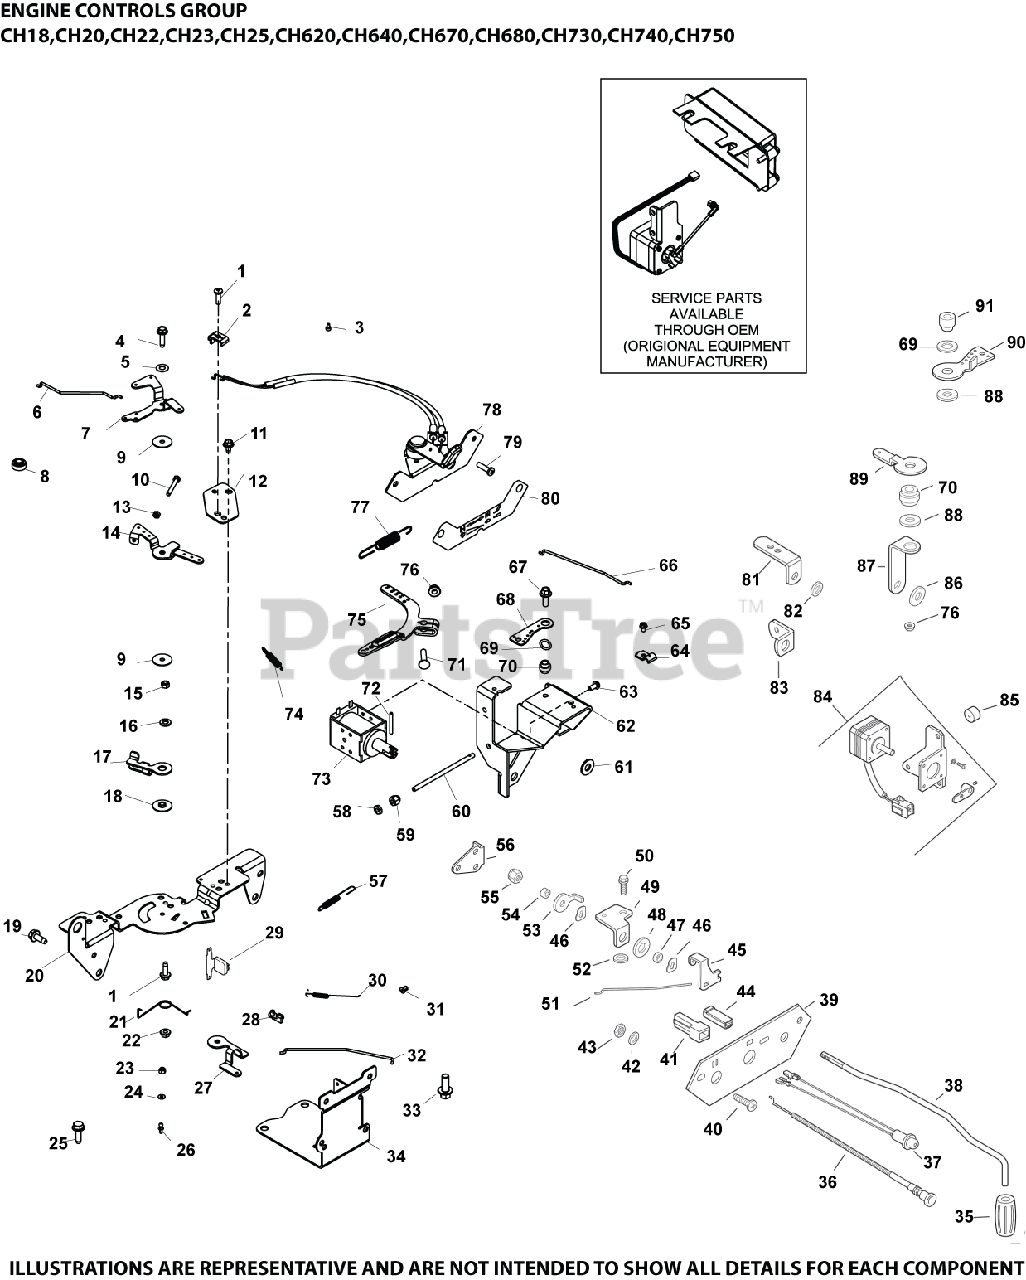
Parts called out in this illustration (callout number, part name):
1	SCREW, THREAD FORMING
2	CLAMP, CABLE
4	SCREW, THREAD FORMING - USE 25 086 473-S
5	WASHER, SPRING 1/4"
6	LINKAGE, CHOKE
7	LEVER, CHOKE
9	WASHER, FLAT 5.5 MM
10	SCREW, CAP M4X.7X30
11	SCREW, FLG THD FRM M5X.8X10
12	BRACKET, CABLE SUPPORT
13	NUT, M4X0.7
14	LEVER, THROTTLE CONTROL
15	NUT, FLG M5X.8
16	WASHER, SPRING LOCK 1/4"
19	SCREW, THREAD FORMING
20	BRACKET, CONTROL
22	NUT, LOCK M5X.8
27	LEVER, THROTTLE ACTUATOR
28	BUSHING, THROTTLE LINKAGE
30	SPRING, LINKAGE
31	BUSHING, LINKAGE RETAINING
32	LINKAGE, THROTTLE
57	SPRING, THROTTLE LIMITER
71	BOLT, RD HD SQ NECK M6X1.0X25
75	LEVER, GOVERNOR - (#2409069S)
76	NUT, FLG M6X1.0
77	SPRING, GOVERNOR (PURPLE)
78	CABLE ASSY, CONTROL - (#2422508S)
80	DECAL, CONTROL PANEL
